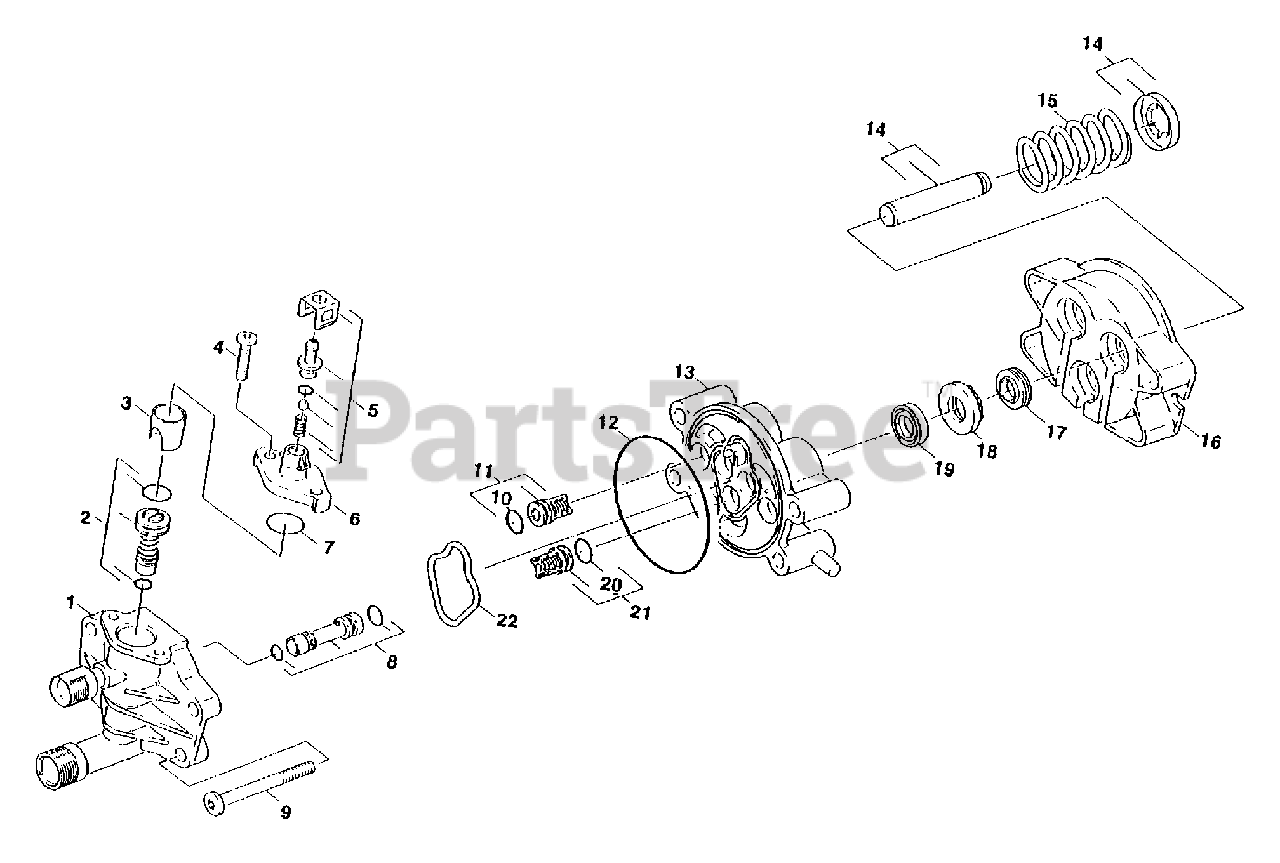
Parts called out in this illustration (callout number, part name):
2	SPILL VALVE
3	SLEEVE
4	SELF-TAPPING SCREW
5	SPARE PARTS KIT
7	19.3 x 2.4mm O-RING
8	NOZZLE INSERT
9	OVAL HEAD SCREW
10	10 x 2.5mm O-RING
11	VALVE
12	76 x 2mm O-RING
13	CYLINDER HEAD
15	HELICAL SPRING
17	GROOVED RING
18	WASHER
19	GROOVED RING
20	O-RING
21	PRESSURE VALVE
22	GASKET
